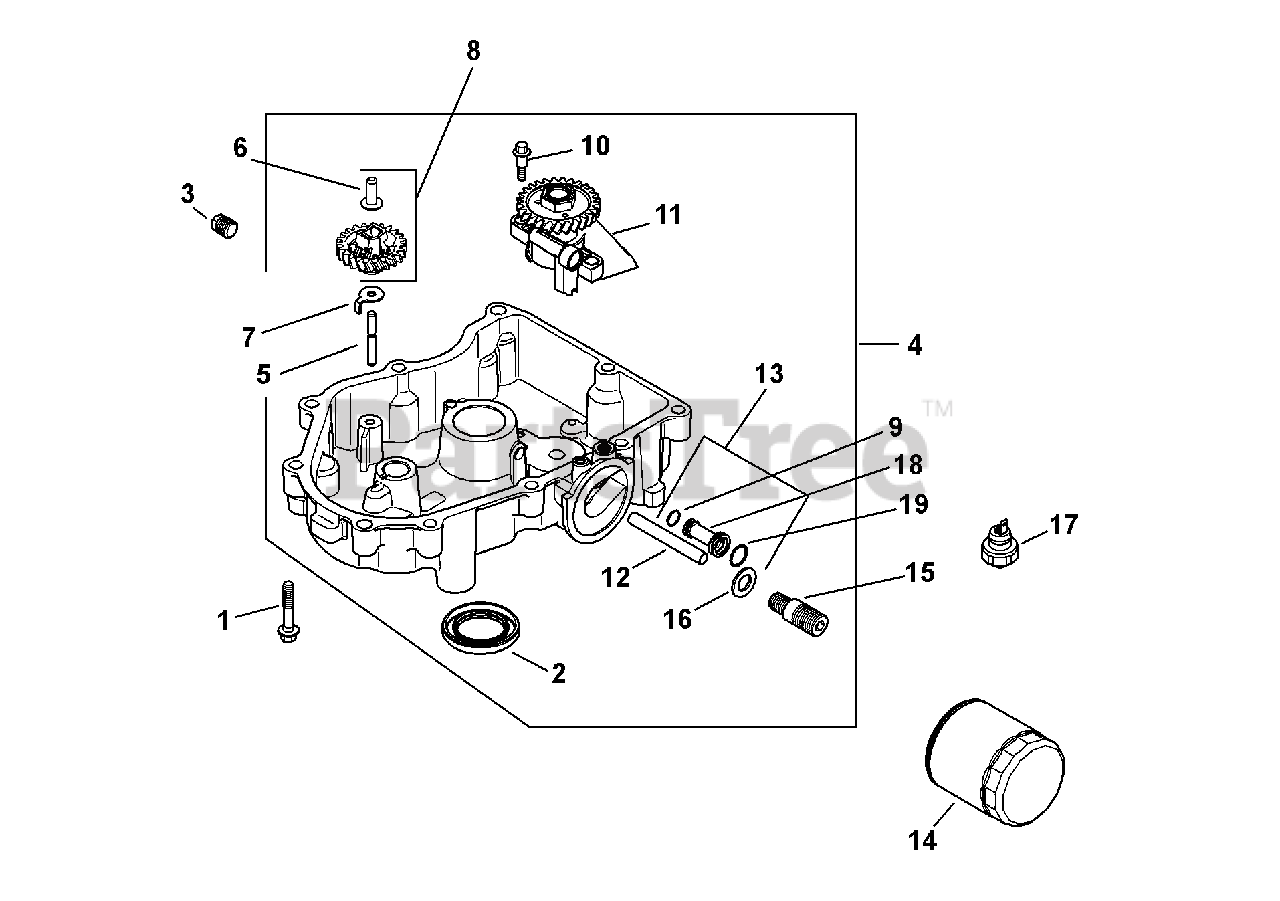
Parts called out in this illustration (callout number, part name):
1	Flange Screw, M8 x 1.25 x 45
2	Oil Seal, 2.38 x 1.45
3	Square Head Pipe Plug, 3/8
4	Oil Pan Assembly
5	Governor Gear Shaft
6	Governor Regulating Pin
8	Governor Gear Kit
9	Oil Pick-Up O-Ring
11	Oil Pump Assembly
12	Oil Feed Tube (Filter to Oil Pan)
13	Oil Feed Tube Assembly
15	Oil Filter Nipple
17	Oil Pressure Switch
18	Oil Feed Tube
